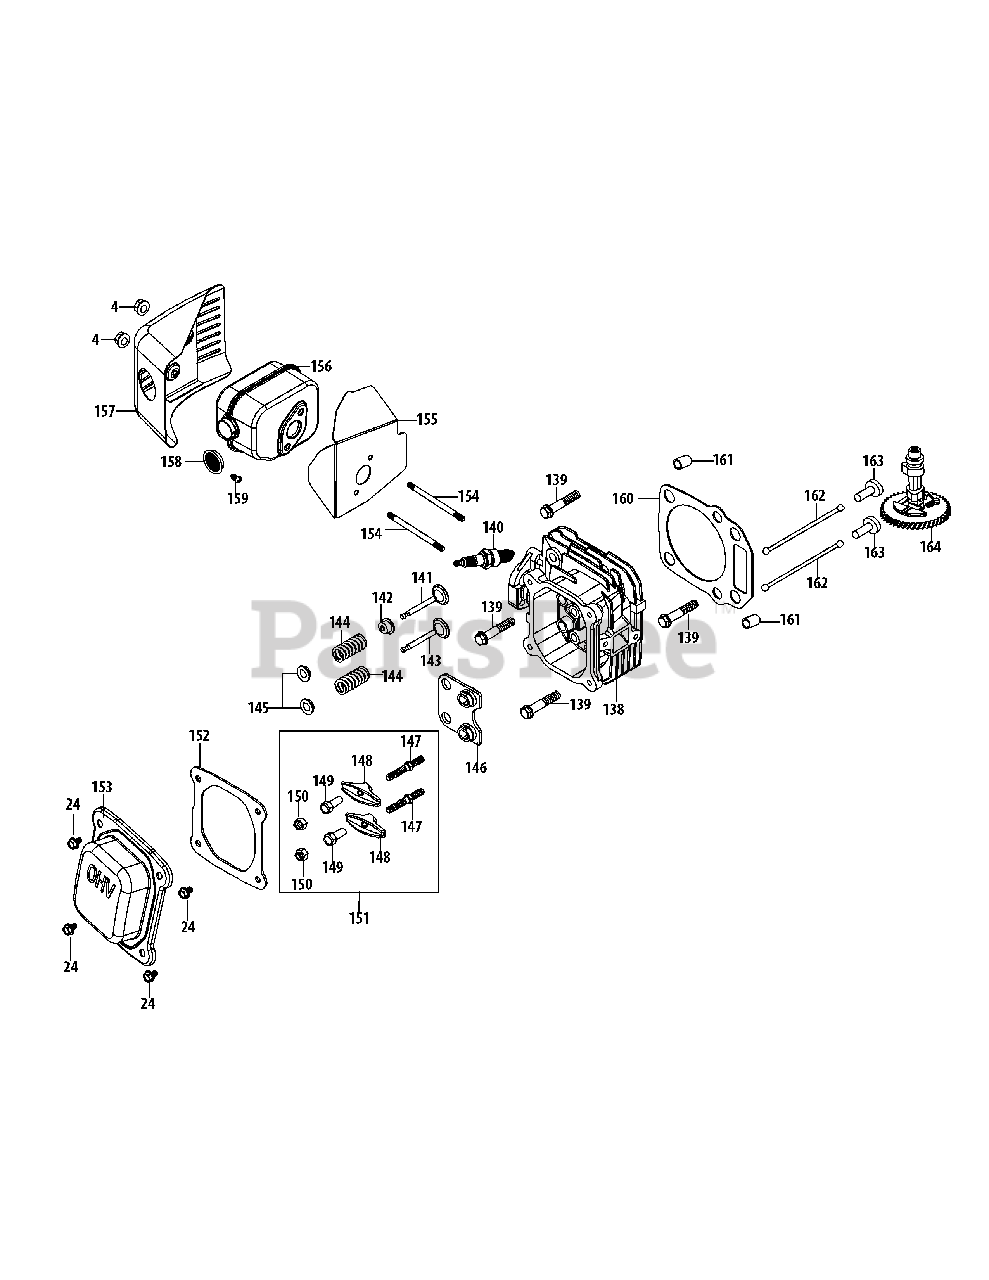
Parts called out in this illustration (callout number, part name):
4	Nut M6X10M
24	Bolt M6X14
138	Cylinder Head Assembly
139	Bolt M8X54 Cylinder Head
140	Spark Plug
142	Intake Valve Seal
144	Valve Spring
145	Valve Spring Retainer
146	Push Rod Guide
147	Rocker Arm Stud
148	Rocker Arm
149	Fulcrum Nut
151	Rocker Arm Assembly
152	Valve Cover Gasket
153	Valve Cover
154	Muffler Stud M6X95
154	Muffler Stud Assemlby
155	Muffler Gasket
156	Muffler Assembly
157	Muffler Shield
158	Spark Arrestor
159	Spark Arrestor Screw
160	Cylinder Head Gasket
161	Cylinder Head Dowel Pin 10×16
162	Push Rod Kit
164	Camshaft Assembly
